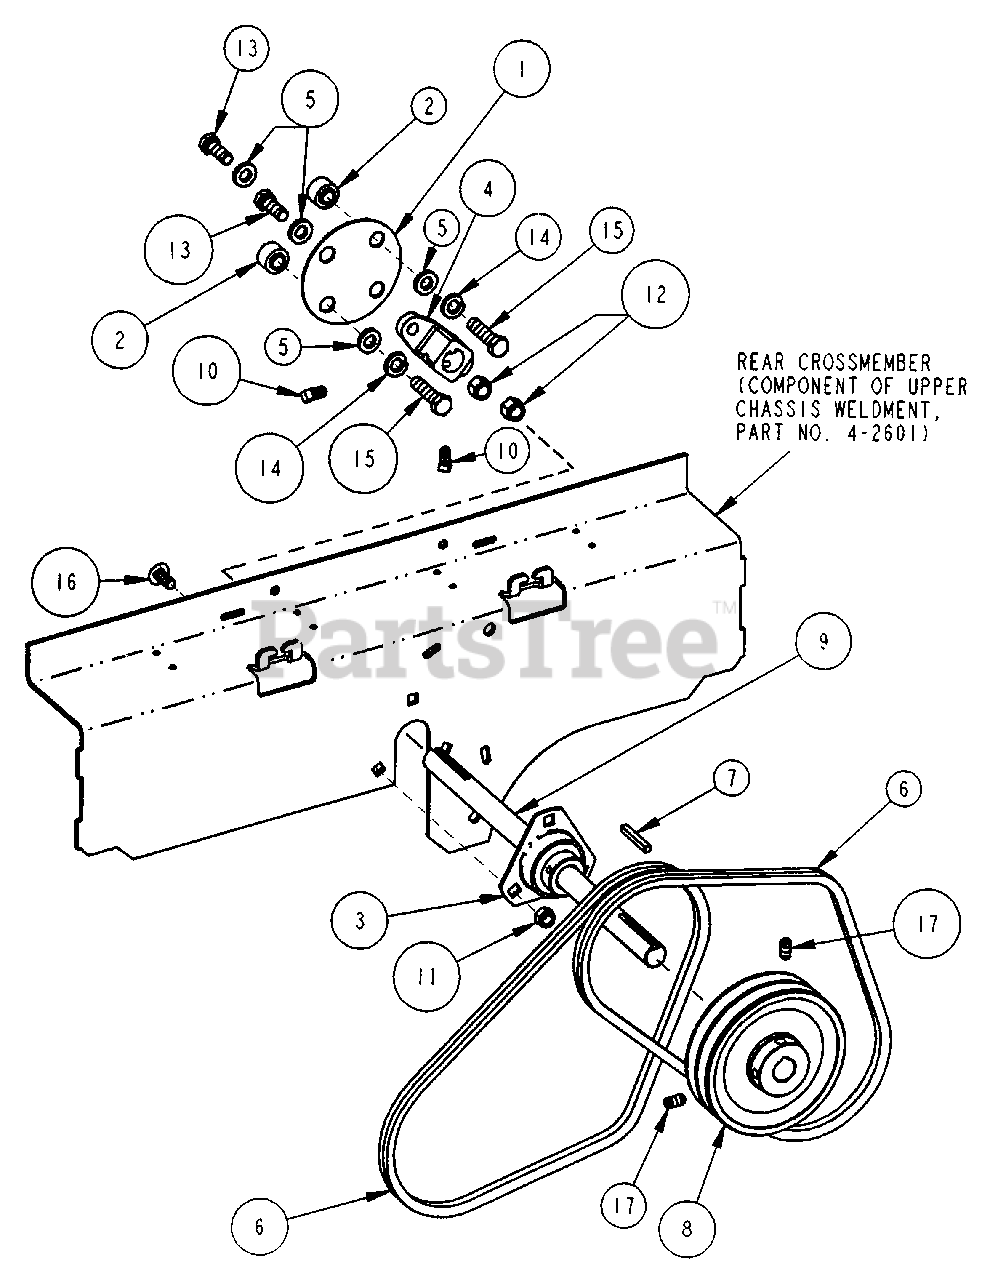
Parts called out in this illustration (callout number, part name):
1	DISC, Flexible
2	SPACER, LT16
3	BEARING, 3/4"
4	HUB, Drive Shaft Adapter
5	WASHER, 13/32 I.D. x 3/4 O.D., Flat
6	BELT, 36-1/2"
7	KEY, 3/16 Square x 1-1/2" Long
8	PULLEY, Cast Iron Dual V 4.95 Effective O.D.
9	DRIVE SHAFT, 3/4"
10	SET SCREW, 5/16-18 x 1/2" Square Head Cup Point
11	NUT, 5/16-18 HEX NYLON LOCK
12	NUT, 3/8-16 HEX NYLON LOCK
13	BOLT, 3/8-16 X 1" GD5 CZ
14	WASHER, 3/8" SPLIT LOCK
15	SCREW, 3/8-16 x 1-1/2" Hex Head Cap, Grade 5
16	BOLT, 5/16-18 x 3/4", Carriage, Grade 5
17	SCREW, 5/16-18 x 5/8", Socket-Head
